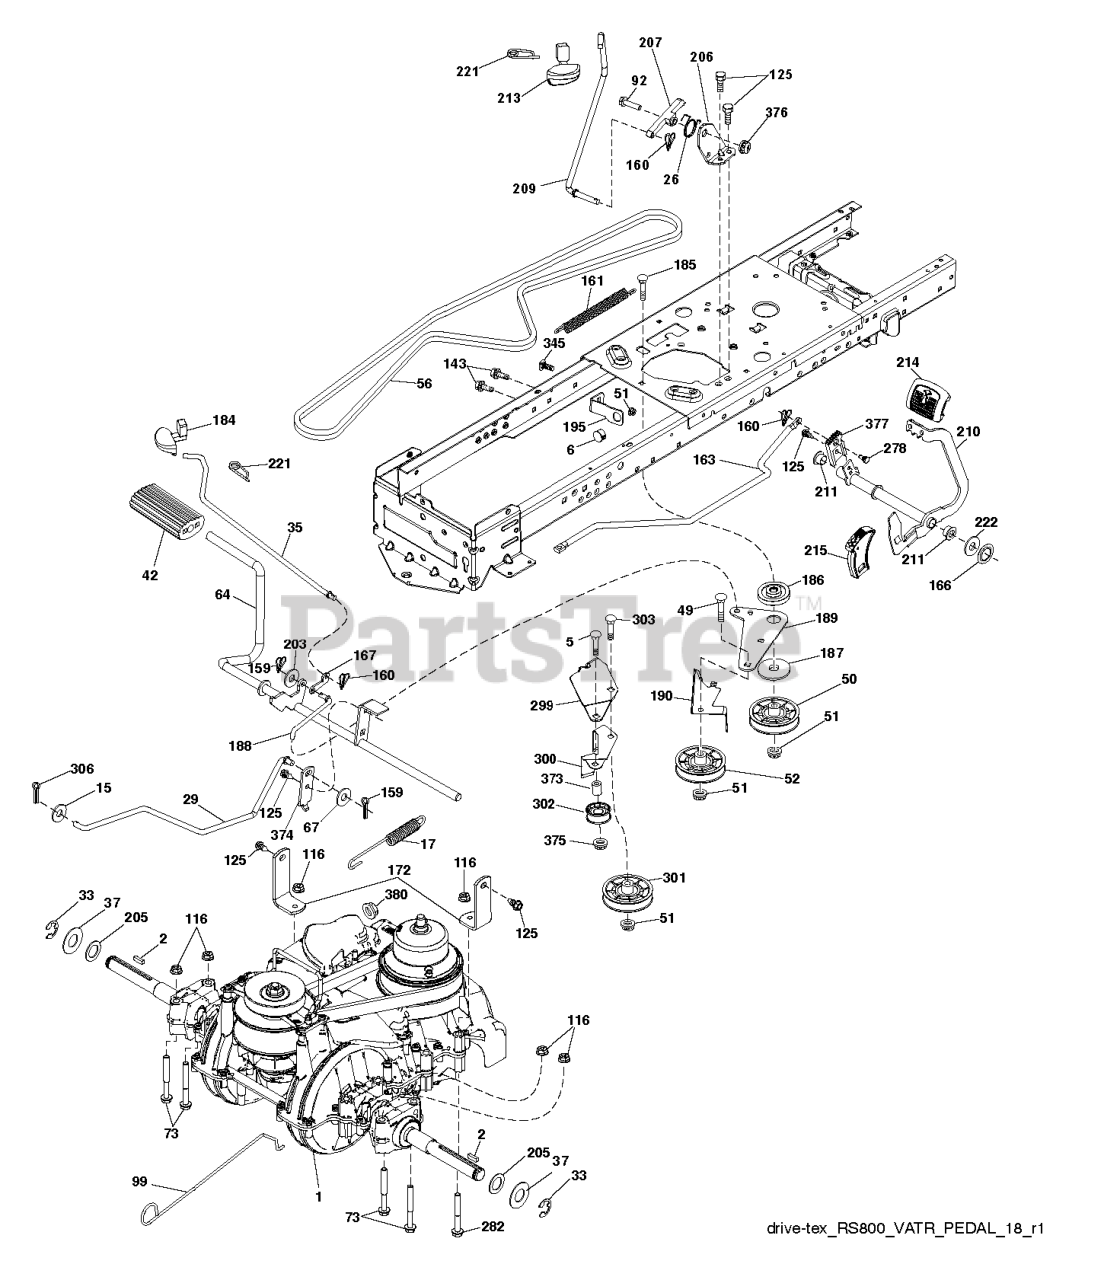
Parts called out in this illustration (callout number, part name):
2	SQUARE KEY
6	BUSHING.SNAP.NYL.BLK.
15	WASHER
17	SPRING.BRAKE.VARIATOR
26	SPRING.RETURN.CRUISE
29	BRAKE.VARIATOR.SD3
35	ROD .BRAKE. PARKING. GT. HUSQ.
37	WASHER.HARDENED
42	PEDAL COVER T
49	BOLT
50	IDLER.FLAT.910.OFFSET
51	NUT LOCK FLG 3/8-16 UNC
52	IDLER.V-GROOVE.910.OFFSET
56	BELT.DRIVE.MOWER.TEX.42"
64	SUBASM.SHAFT.PEDAL.BRAKE
67	WASHER.NYLON;13/32X13/16X.109
73	BOLT HEX 5/16-18 GR 5
92	BOLT
99	ROD.BYPASS.VARIATOR.GEN2
116	NUT LOCK HEX FLANGE 5/16-18
125	SCREW
143	Screw 5/16-18 x 1/2 Hex, Self Tapping 5/16-18 x 1/2
159	COTTER PIN
160	RETAINER CLIP
161	SPRING, RETURN LT
163	ROD.CONTROL.PEDAL.VARIATOR
166	NUT.PUSH.625
167	LATCH.BRAKE.SPRING
172	STRAP.TORQUE.VARIATOR
184	HANDLE.PARKING.BRAKE.H (BLK)
186	SPACER.RETAINER
187	WASHER 12/32X2X10GA
188	LINK.CLUTCH.GROUND DRIVE.LONG
189	BELLCRANK.GROUND.DRIVE.TEX.
190	KEEPER.BELLCRANK.DRIVE
195	BRACKET.BRAKE.BRAKE.VAR.SD
203	WASHER
206	BRACKET.MOUNT.CRUISE.LATCH
207	LATCH.CONTROL.CRUISE.VARIATOR
209	ROD.CONTROL.CRUISE.GT.
210	PEDAL.ASM.ROCKET.VARIATOR.LT
211	BEARING.NYLON
213	KNOB.CONTROL.CRUSIE.HU
214	PEDAL.FORWARD.PAD.TEX
215	CAP.PEDAL.REVERSE.VARIATOR
221	RETAINER.SPRING.CLIP.H
222	WASHER 21/32 X 1-1/4 X 10 GA.
278	BOLT CRUISE VARIATOR
282	BOLT HEX FLGHD 5/16-18X3 GR. 5
299	BRACKET.MOUNT.IDLERS
300	KEEPER.IDLERS.REAR.VARIATOR
301	PULLEY.IDLER.V-GROOVE
302	PULLEY.IDLER.FLAT.2"
303	BOLT CARRIAGE
306	PIN COTTER
345	BOLT
373	SPACER.IDLER
374	ARM.CONTROL.BRAKE
375	LOCKNUT
376	NUT.FLANGE.HEX.5/16X18.BLACK
377	GEAR.SECTOR.CONTROL.CRUISE.VAR
378	NUT.PUSH.8MM
